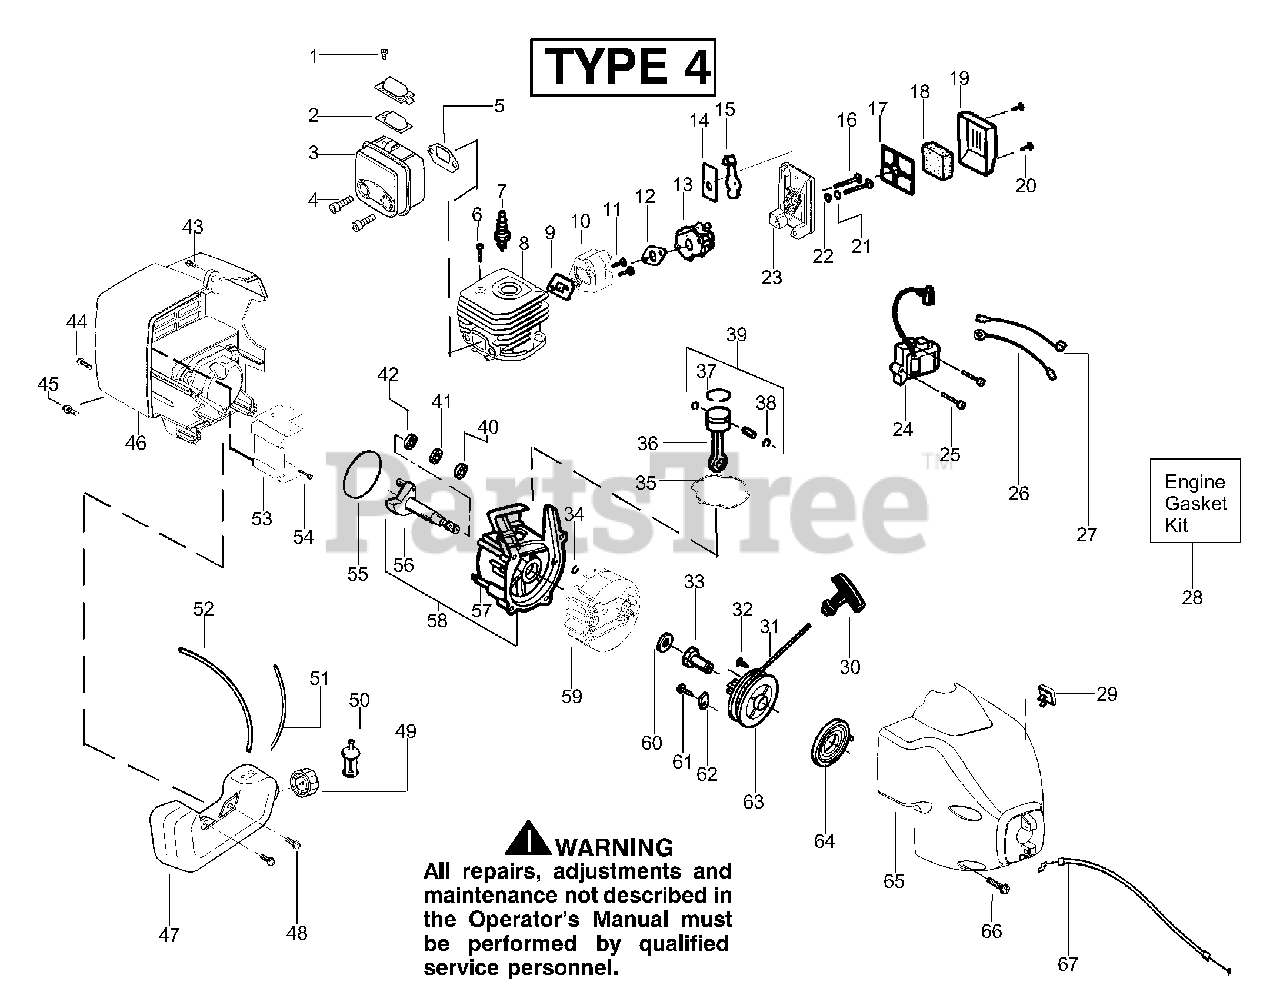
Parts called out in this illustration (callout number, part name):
1	Screw-screen
2	Kit-Spark Arrestor
3	Kit-Muffler
4	Bolt-Muffler
5	Gasket-Muffler (kit)
6	Screw-Cylinder
7	Spark Plug (RCJ-6Y)
8	Kit-Cylinder
9	Gasket-Cyl/Carb.(kit)
10	Carb. Adapter
11	Screw-Carb Adptr.
12	Gasket-Carb.(kit)
13	Kit-Carb. Ass'y. (C1U-W10B)
14	Choke Plate
15	Choke Shutter
16	Screw-Carburetor
17	Filter Support Plate
18	Air FIlter Foam
19	Air Filter Cover
20	Screw-Air Box
21	Choke Spacer
24	Ignition Module
25	Screw-Ignit. Module
26	Assy-Ground Wire
27	Assy-Lead Wire
28	Kit-Engine Gasket
29	Kit-Switch-Off/On
30	Handle-Starter
31	Kit-Rope
33	Coupling-Drive
34	Ret. Ring/C'shaft
35	Seal-Cylinder(kit)
36	Assy-Connecting Rod
37	Ring-Piston
38	Retainer-Piston Pin
39	Kit-Piston
40	Bearing-Outer
41	Seal-C'case
42	Bearing-Inner
43	Screw-Shd/Fan Hsg
44	Screw
46	Rear Shroud
47	Assy-Fuel Tank
48	Retainer-Tank
49	Assy-Fuel Cap
50	Assy-Fuel Pickup
51	Fuel Line (Small)
52	Fuel Line (Large)
53	Shield-Heat
54	Screw-Heat Shield
55	O-ring-C'case(kit)
56	Assy-Crankshaft
57	Assy-Crankcase
58	Assy-C'case/C'shaft
59	Assy-Flywheel
60	Washer-Flat
61	Screw-Pulley
62	Retainer-Pulley
63	Kit-Starter Pulley
64	Spring-Starter
65	Assy.-Fan Hsg.
66	Screw
67	Assy-Throttle Cable
